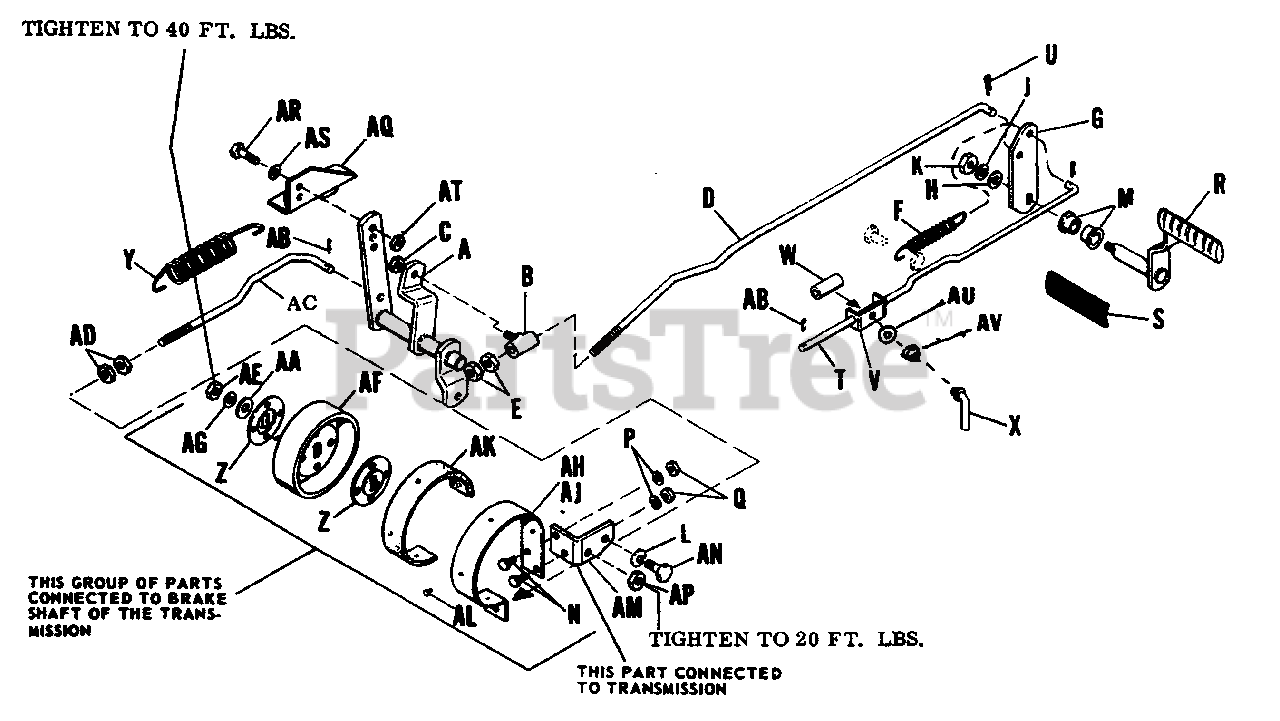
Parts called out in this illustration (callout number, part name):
A	Pivot Lever Assembly
B	Rod Guide Assembly
C	Hex Lock Nut, 5/16"-18
D	Brake and Clutch Rod
E	Hex Nut, 5/16"-18
F	Tension Spring
G	Foot Pedal Arm
H	Washer, Plain, 3/8"
J	Lock Washer, 3/8"
K	Hex Nut, 3/8"-16
L	Lock Washer, 3/8"
N	Hex Capscrew, 1/4"-20 x 3/4" lg.
P	Lock Washer, 1/4"
Q	Hex Nut, 1/4"-20
R	Foot Pedal Assembly
S	Pedal Pad
T	Parking Brake Rod
U	Cotter Pin, 1/8" x 3/4" lg.
V	Parking Brake Bracket Assy.
X	Parking Brake Lock
Y	Tension Spring
Z	Special Washer
AA	Washer, Plain, 3/8"
AB	Cotter Pin, 3/32" x 3/4" lg.
AC	Brake Rod
AD	Hex Nut, 3/8"-16
AE	Hex Nut, 7/16"-14
AF	Brake Drum
AG	Lock Washer, 7/16"
AH	Brake Band Assembly
AK	Brake Lining
AM	Brake Band Bracket
AN	Hex Capscrew, 3/8"-16 x 1" lg.
AP	Hex Nut, 3/8"-16
AQ	Spring Bracket
AR	Hex Capscrew, 5/16"-18 x 3/4" lg.
AS	Lock Washer, 5/16"
AT	Hex Nut, 5/16"-18
AU	Plain Washer, 7/16"
